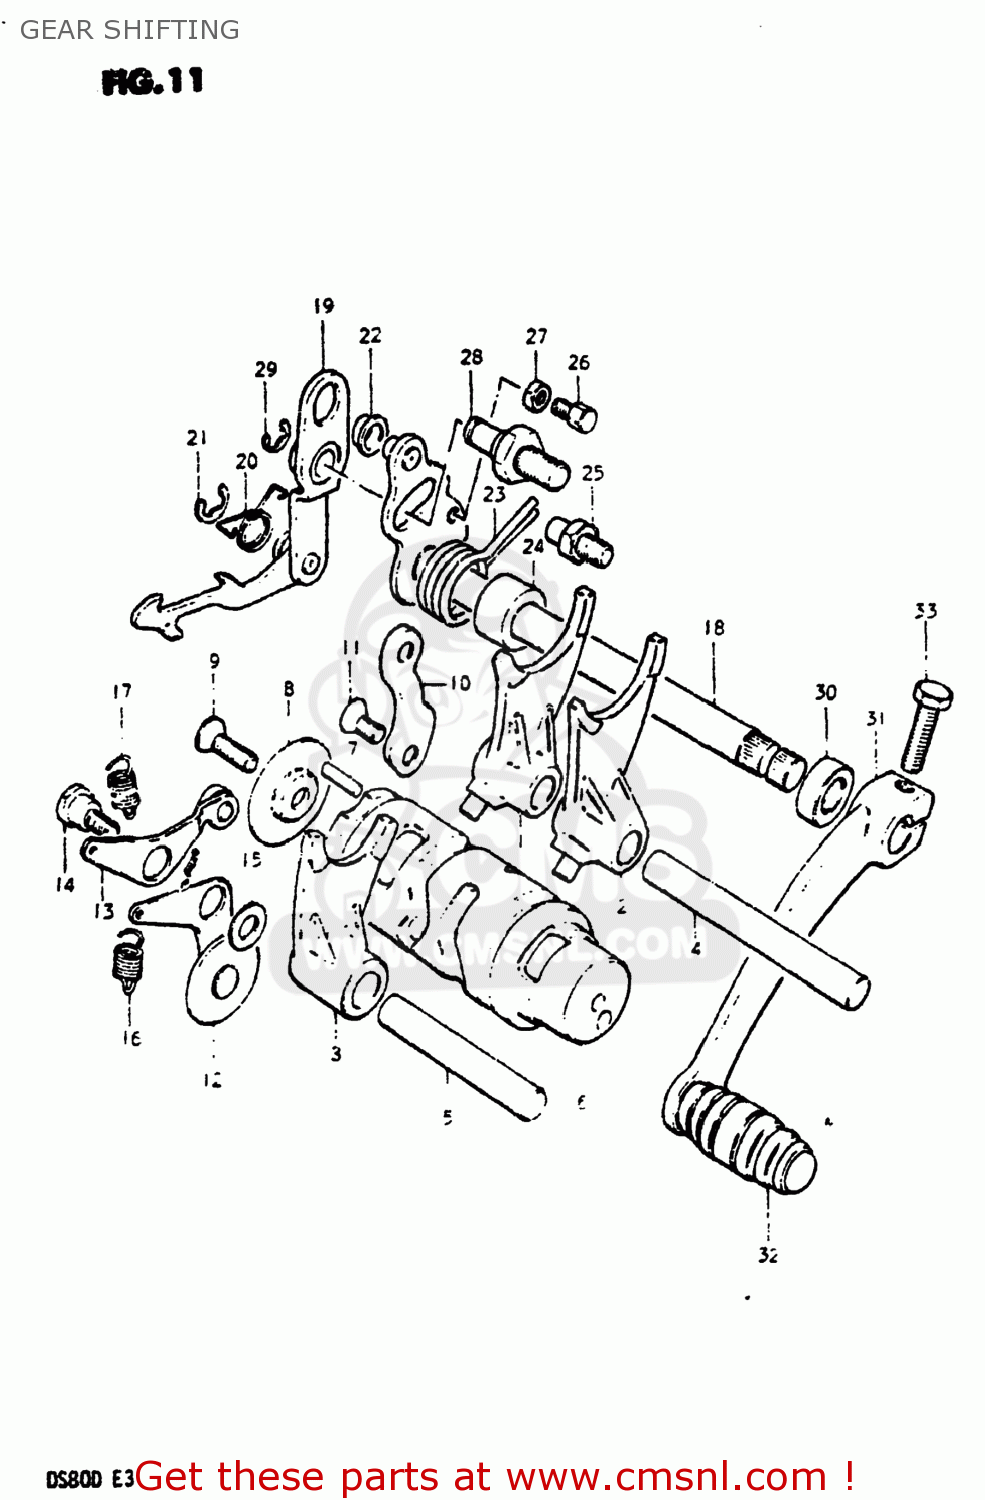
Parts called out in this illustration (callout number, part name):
1	FORK,GEAR SHIFT NO.1
2	FORK,GEAR SHIFT NO.2
3	FORK,GEAR SHIFT NO.2
4	SHAFT,GEAR SHIFT FORK
5	SHAFT,GEAR SHIFT FORK
6	CAM,GEAR SHIFT
7	PIN
8	RETAINER,GEAR SHIFT CAM DR PIN
9	SCREW
10	GUIDE,GEAR SHIFT CAM
11	SCREW
12	STOPPER,GEAR SHIFT CAM
13	STOPPER,GEAR SHIFT CAM NEUTRAL
14	BOLT(6X18.3)
15	WASHER
16	SPRING
17	SPRING
18	SHAFT,GEAR SHIFT
19	PAWL,GEAR SHIFT
20	SPRING
21	E RING
22	SPACER(7X10X5)
23	SPRING
24	SPACER(12X20X15.3)
25	STOPPER,GEAR SHIFT CAM
26	BOLT,GEAR SHAFT RETURN SPR SET
27	NUT 6MM
28	STOPPER,GEAR SHIFT CAM
29	E RING 6MM
30	OIL SEAL
31	LEVER ASSEMBLY,GEAR SHIFTING
32	RUBBER,GEAR SHIFT PEDAL
33	BOLT
